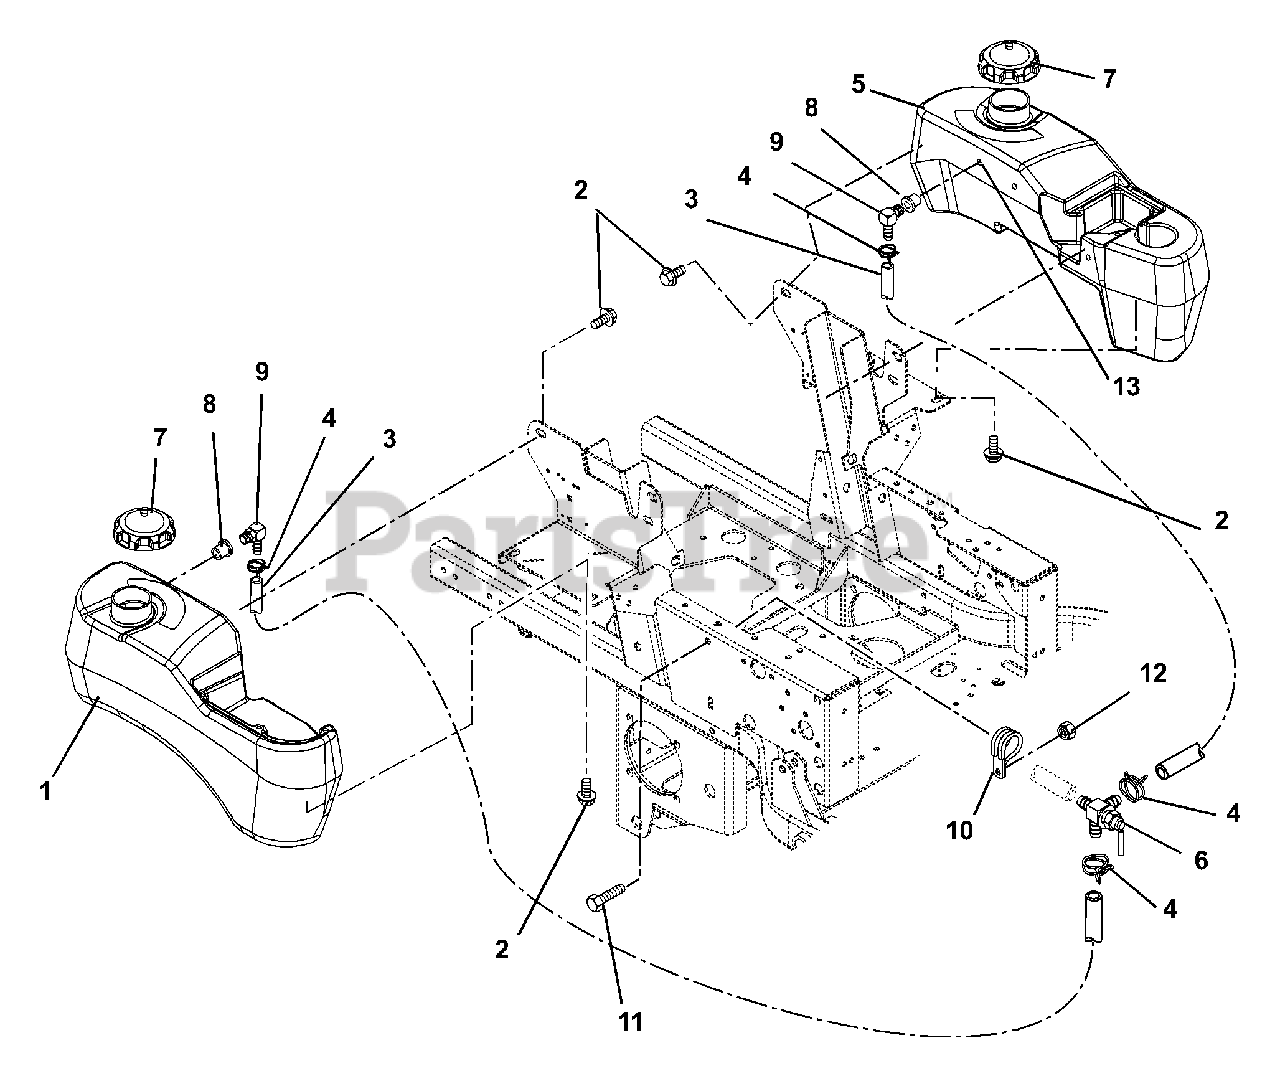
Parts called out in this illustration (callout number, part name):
1	Tank, Gas - Right Hand
2	Bolt, Hex .31-18 x .75 Grade 5
3	Gas Line, Bulk .25" ID
4	Hose, Clamp
5	Tank, Left Hand Fuel
6	Valve, Fuel
7	Cap, Gas
8	Grommet, Orange
9	Fuel Tank Fitting
10	Clamp, Cushioned Steel
11	Bolt, Hex .38-16 x 1.00 Grade 5
12	Nut, Locking Top Flange .38-16
13	20" Fuel Line Kit (inside of tank)
